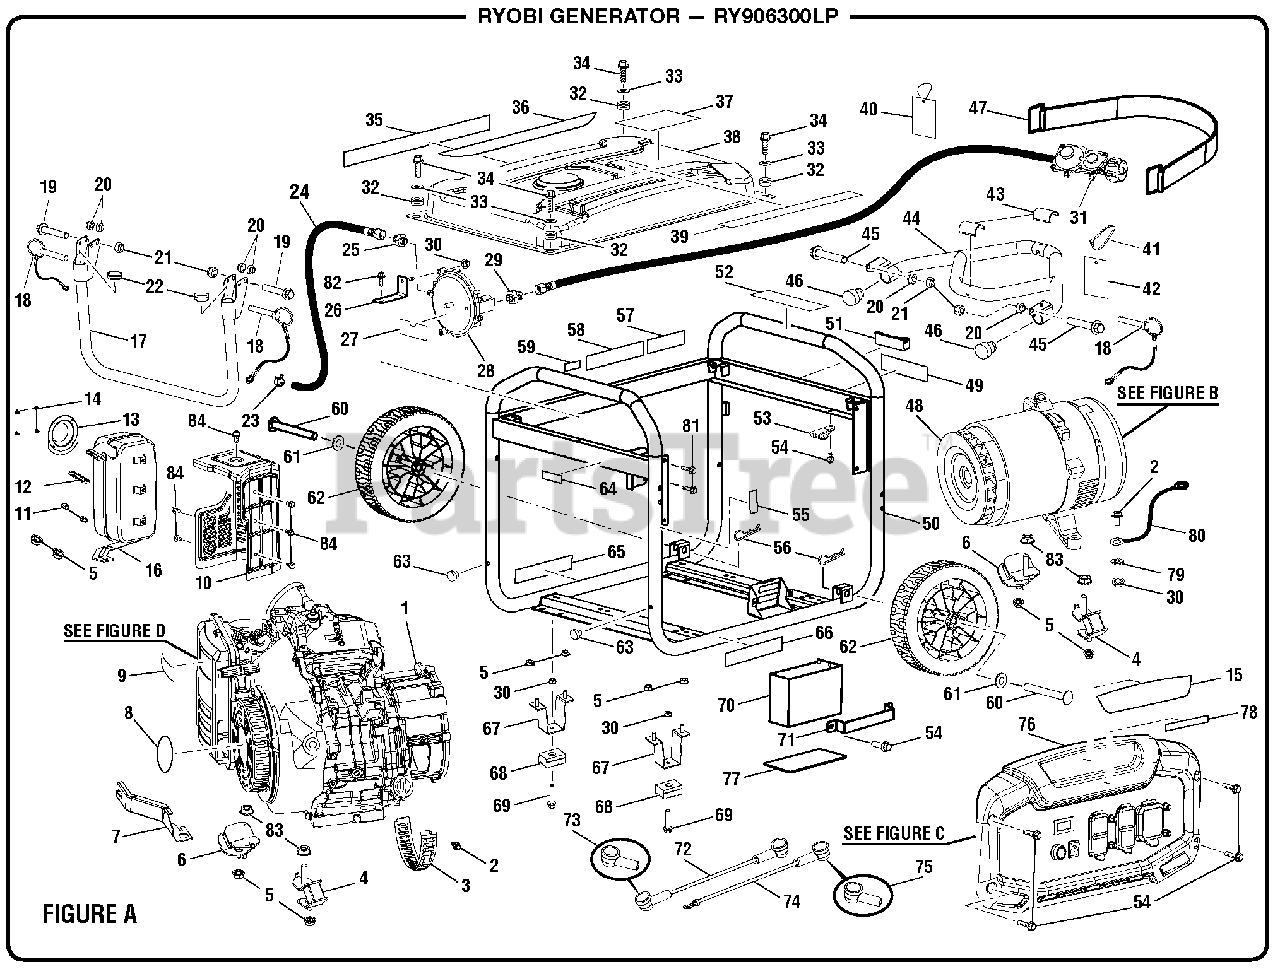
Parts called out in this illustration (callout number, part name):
2	Bolt (M6 x 12 mm)
3	Crank Case Guard Cover
4	Small Isolator
5	Flange Lock Nut (M8)
6	Large Isolator
7	Air Cleaner Bracket
8	Engine Recoil Label
9	Choke Label
10	Heat Shield
11	Lock Washer
12	Exhaust Gasket
13	Spark Arrestor Screen
14	Screw (8-32 x 3/8 in.)
15	Performance Label
17	Handle Assembly
18	Release Pin
19	Bolt (M8 x 50 mm)
21	Lock Nut (M8)
22	Handle End Cap
23	LP Hose Clamp
25	Outlet (Brass Fitting)
27	Small Primer Label
28	Propane Regulator Assembly (Stage 2)
29	Inlet (Brass Fitting)
30	Hex Nut (M6)
31	Propane Regulator Assembly (Stage 1,T8)
32	Fuel Tank Bushing
33	Fuel Tank Washer
34	Bolt (M6 x 25 mm)
35	LP Danger/Warning Label
36	Danger/Warning Icon Label
37	CPSC Label
38	Fuel Tank Insert
39	Quick Start Label
40	Hang Tag Label Warning w/Icons
41	Zip Tie (5.5 in.)
42	Hang Tag Warning Label
43	Rubber Flap
44	LPG Tank Bracket
45	Screw (Hex. Hd.)
46	Tank Bracket Plug
47	Tank Strap
48	Gen Head Assembly (See Figure B)
49	Ground Warning Label
51	LPG Tank Bumper
52	Fire Danger Label
53	Fuel Line Clamp
54	Bolt (M6 x 16 mm)
55	Lock Pin Label
56	Hitch Pin
57	Hot Surface Label (Trilingual)
58	Fire Distance Label
59	Inquires Label (Ryobi)
60	Washer (M10)
62	Handle Isolator
63	Large Primer Button Label
64	Combustion Warning Label
65	Check Lubricant Label
66	Frame Support
67	Isolation Pad
68	Bolt (M6 x 25 mm)
69	Battery
70	Battery Bracket
71	Red Battery Cable (+)
72	Rubber Boot (Red)
73	Black Battery Cable (-)
74	Rubber Boot (Black)
75	Control Panel Assembly
76	(See Figure C)
77	Battery Tray Gasket
78	Electric Start Label
79	Star Washer
80	Frame Ground Wire
82	Bolt (M6 x 12 mm)
83	Hex Nut (M10)
84	Bolt (M6 x 9 mm, Hex Hd.)
